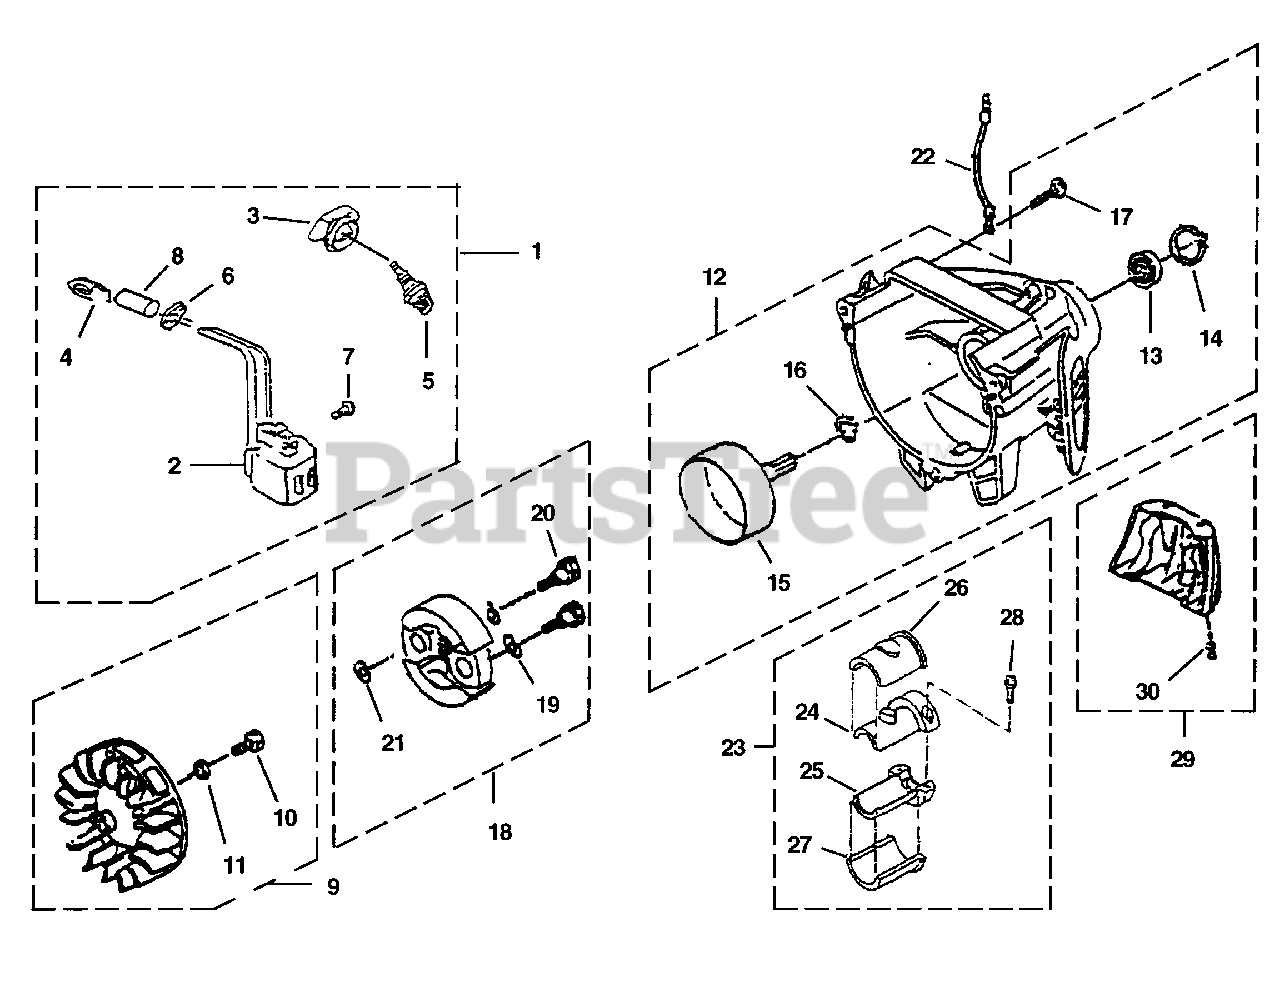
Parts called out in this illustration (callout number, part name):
1	IGNITION KIT
2	MODULE-Ignition
3	CAP-Plug
4	SPRING-Plug Cap
5	SPARK PLUG
7	SCREW ASSEMBLY
9	ROTOR ASSEMBLY
10	BOLT ASSEMBLY
12	CLUTCH HOUSING
13	BEARING-Ball
14	SNAP RING-Inner
15	CLUTCH DRUM
16	SNAP RING-Outer
17	SCREW-Socket Hd (M5 x 20)
18	CLUTCH ASSEMBLY
20	BOLT-Clutch
23	DRIVESHAFT ISOLATOR ASSEMBLY
26	ISOLATOR
27	ISOLATOR
28	SCREW-Socket Hd (M5 x 18 SW)
29	ENGINE STAND
30	SCREW ASSEMBLY (M5 x 14)
